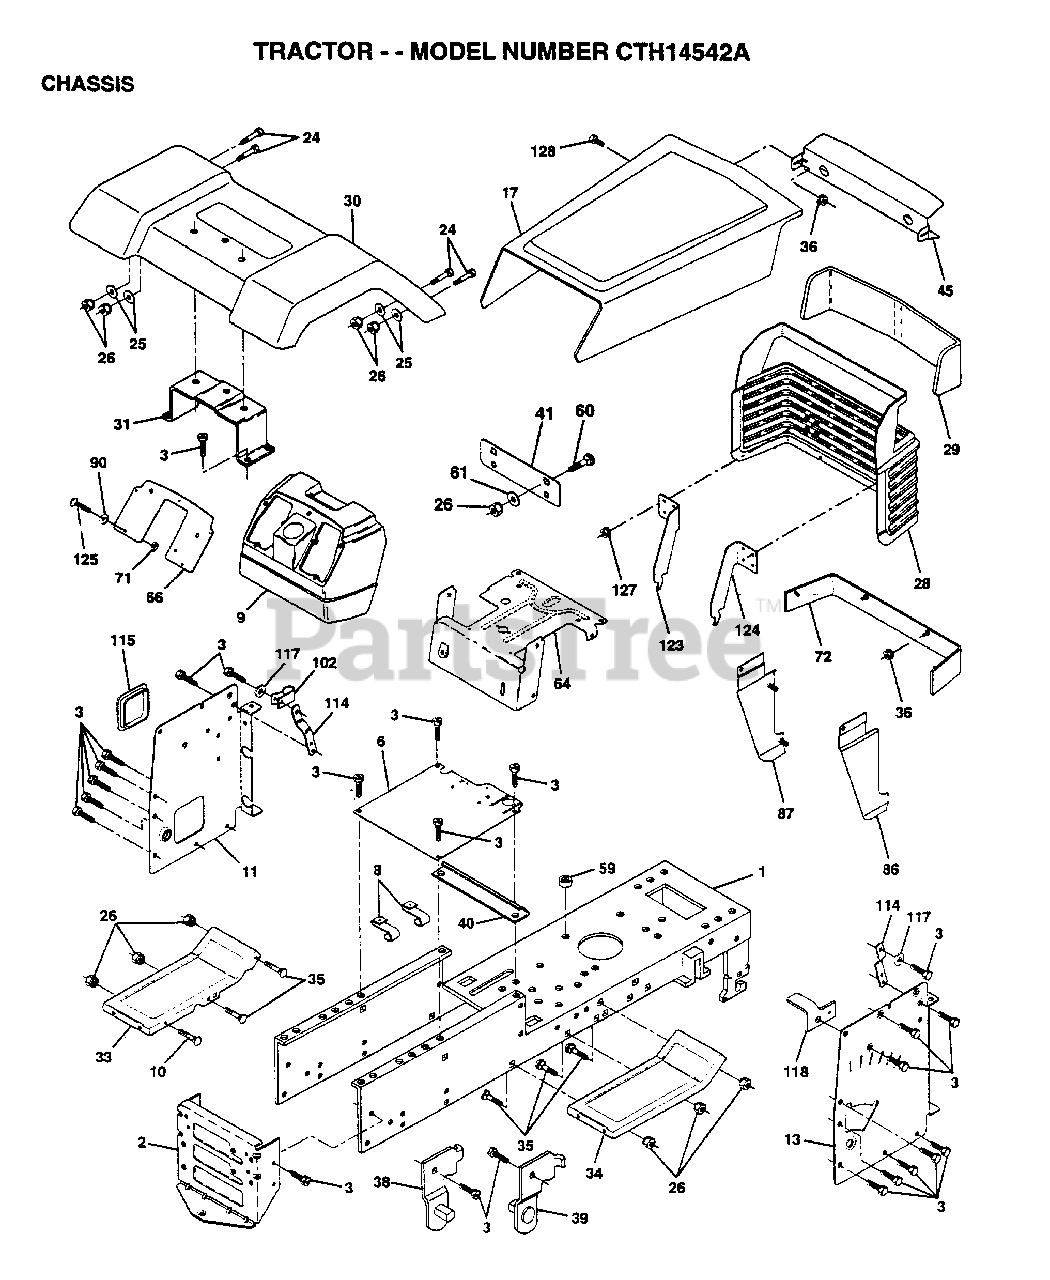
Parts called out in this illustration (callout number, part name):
1	CHASSIS.WLD.11GA
3	SCREW
8	"CLIP,INSULATOR"
9	DASH.PLASTIC.BLK
11	PANEL.DASH.LH.
13	PANEL.DASH.RH.
17	HOOD/GRILLE ASM
24	BOLT
25	WASHER
26	NUT
28	GRILLE ASM WELD
31	BRACKET SUPT FEND
33	FOOTREST.LH.LT/GT
34	FOOTREST.RH.LT/GT
35	BOLT
36	PAL NUT LT
38	BRACKET ASM LH
39	BRACKET ASM RH
40	SPACER FENDER LT
41	PLATE EXTEN FEND
60	BOLT
61	WASHER
66	PLATE DASH SILKSC
71	NUT HXKEP 1/4X20
72	STRAP FENDER ASM
86	PANEL SIDE RH ASM
87	PANEL SIDE LH ASM
90	WASHER PM
102	CLIP T
114	BRACKET.SUPT.DASH
115	COVER ACCESS
117	WASHER.SERRATED.
118	BRACKET.CLUTCH.MC
124	BRACKET.PICK.RH
125	SCREW
127	PAL NUT
128	SCREW SPECIAL
